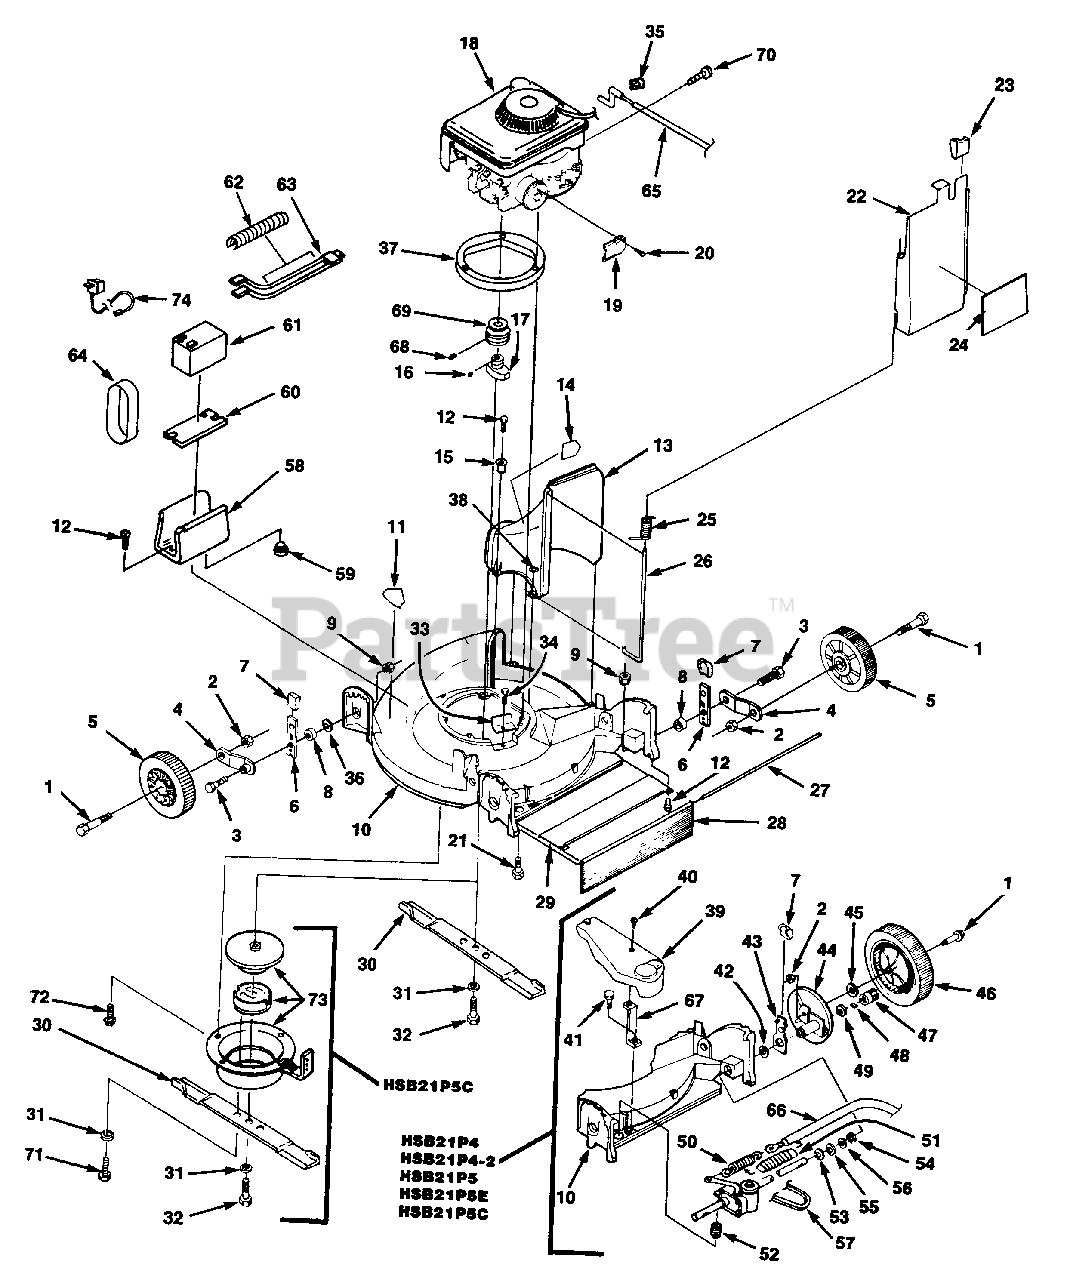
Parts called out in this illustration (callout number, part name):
1	AXLE ASSY.
2	HEX NUT (CM20P4) TBO
3	Bolt, TBO
4	ARM - Wheel hgt. adj.
5	WHEEL & TIRE
6	Index Front Spring, Tbo
7	KNOB
8	SPACER - Wheel hgt. adj.
9	HEX WASHER NUT-TBO
11	DECAL- Foot pad
12	SCREW - 1/4-20 x 3/4" Hex Tap
14	DECAL-CPSC
17	ADAPTER TBO
19	DEFLECTOR
20	Screw (Hex Head)
21	SCREW- (3/8-16 x 2 1/4")
22	DOOR - Chute
23	KNOB
24	DECAL - Door Warning
25	SPRING - Chute door
26	PIN - Hinge
27	ROD - Trailing Shield
28	FLAP - Drag
29	COVER- Rear
30	BAR-Cutter
31	WASHER - Lock 3/8"
32	Screw-Hex hd. 3/8-24 x 2"
33	COVER- Belt opening
34	SCREW-(1/4-20 X 1/2")
35	STOP - Rope
36	FLAT WASHER(HSD'S) TBO
37	RING- Engine
38	Washer, Flat, 7.25 ID x 16 OD
39	COVER-Drive
40	Screw - phillips 1/4-20 x 3/4
41	SCREW - Hex #10-16
42	SPACER - Rear hgt. adj.
43	INDEX SPRING & PIN
44	DRIVE WHEEL SUPPORT-TBO
46	DRIVE WHEEL TBO
47	R.H.PINION (HM20P5) TBO
48	DRIVE PIN
49	WASHER-TBO
50	SPRING - Ext.
51	COVER - Spring
52	SPRING - Compression
57	BELT- Drive
58	HOLDER- Battery
59	BUMPER
60	PAD - battery rubber
62	COVER - Harness
63	LEAD
64	BAND - Rubber
65	ENGINE - Control
66	CONTROL CABLE TBO
70	SCREW
71	SCREW-Hex hd. 3/8-16 x 1"
72	SCREW- (5/16-18)
74	BATTERY CHARGER (120V)
